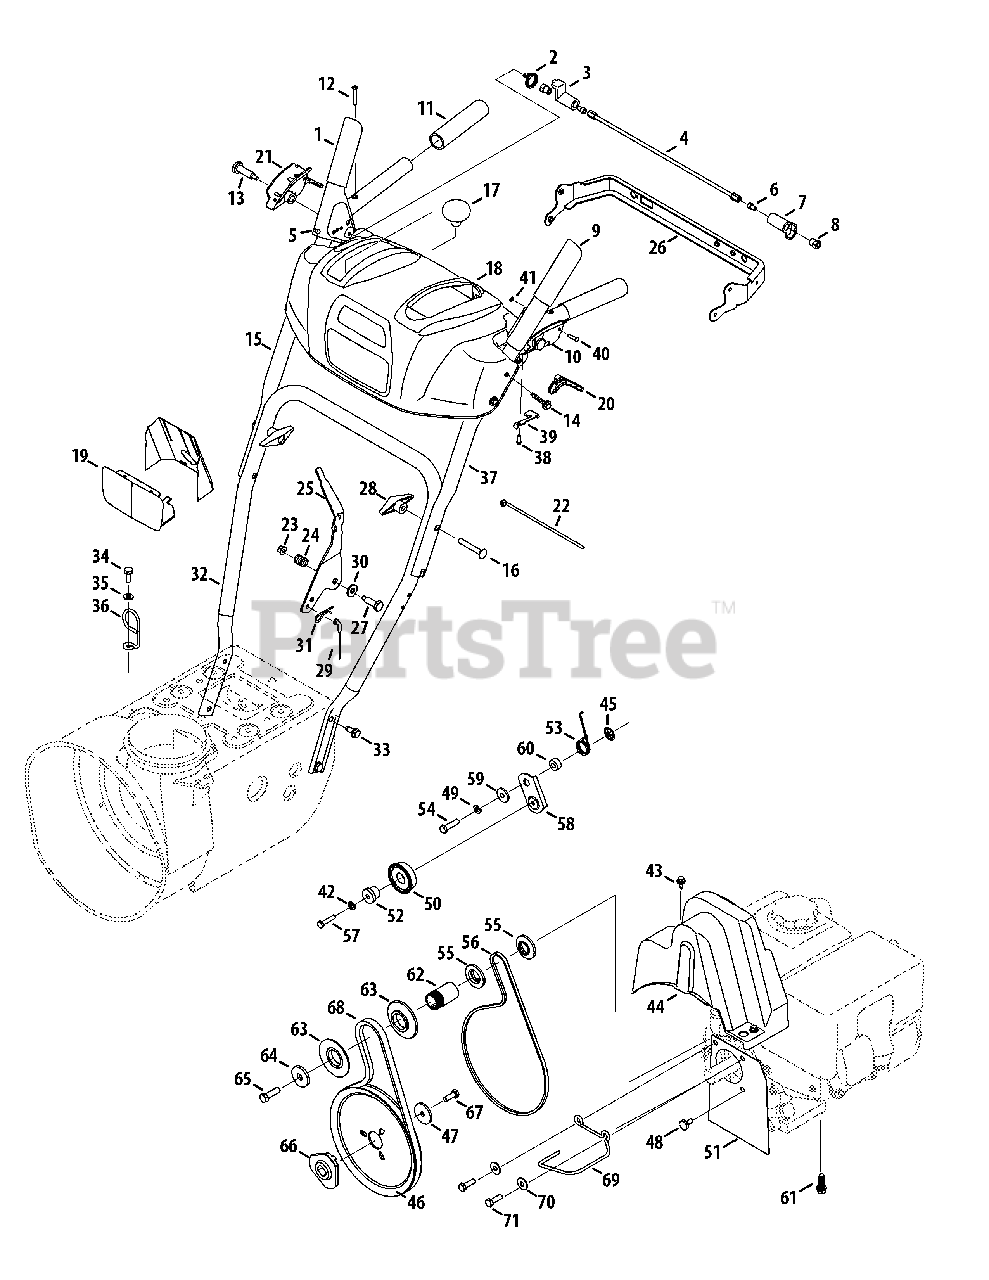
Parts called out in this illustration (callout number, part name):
1	Handle Engagement Ass’y RH
2	Torsion Spring
3	Lock Plate
4	Pivot Rod
5	Rubber Bumper
6	Screw, 1/4-20 x .500
7	Clutch Lock Cam
8	Shoulder Nut, 1/4-20
9	Handle Engagement Assembly LH
10	Handle Clutch Lock LH Assembly
11	Handle Grip
12	Screw, #10-24 x 0.375
13	Shoulder Screw, 1/4-20
14	Screw, 1/4-20 x 1.625
15	Upper Handle RH
16	Carriage Screw, 5/16-18 x 2.25
17	Shift Knob
18	Handle Panel
20	Steering Control
21	Handle Clutch Lock RH Assembly
22	Cable Tie
23	Flange Lock Nut, 1/4-20
24	Compression Spring
25	Shift Lever
26	0637 Panel Bracket
27	Shoulder Screw
28	Wing Knob
29	Speed Selector Cable
30	Flat Washer
31	Click Pin
32	Lower Handle
33	Screw, 5/16-18 x 0.75
34	Screw, M8-1.25
35	Flat Washer, .330 x .630 x .0635
36	Cable Control Wire
37	Upper Handle LH
38	Screw, #8-16 x 0.50
39	Clutch Lock Spring
40	Pin, 3/16
41	Retainer Ring
42	Lock Washer
43	AB Screw, 1/4-20 x 0.625
44	Belt Cover
45	Push-on Nut
46	Auger Pulley
47	Flat Washer
48	Shoulder Screw
49	Lock Washer
50	Idler Pulley Assembly
51	Plt., Cvr.
52	Spacer
53	Torsion Spring
54	Hex Screw, 5/16-24 x 1.25
55	Pulley Half
56	Belt, Wheel Drive
57	TT Screw, 1/4-20 x 1.25
58	Drive Clutch Idler Bracket
59	Shoulder Spacer
61	TT Sems Screw, 3/8-16 x 1.0
62	Spacer
63	Pulley Half
64	Flat Washer
65	Hex Bolt, 3/8-24 x 1.25
66	Pulley Adapter
67	Hex Bolt, 5/16-24 x 0.875
68	V-Belt,.500 x 35.00 Lg
69	Belt Guide
70	Flat Washer, .349 x .879 x .063
71	Screw, 5/16-24 x 1.00
